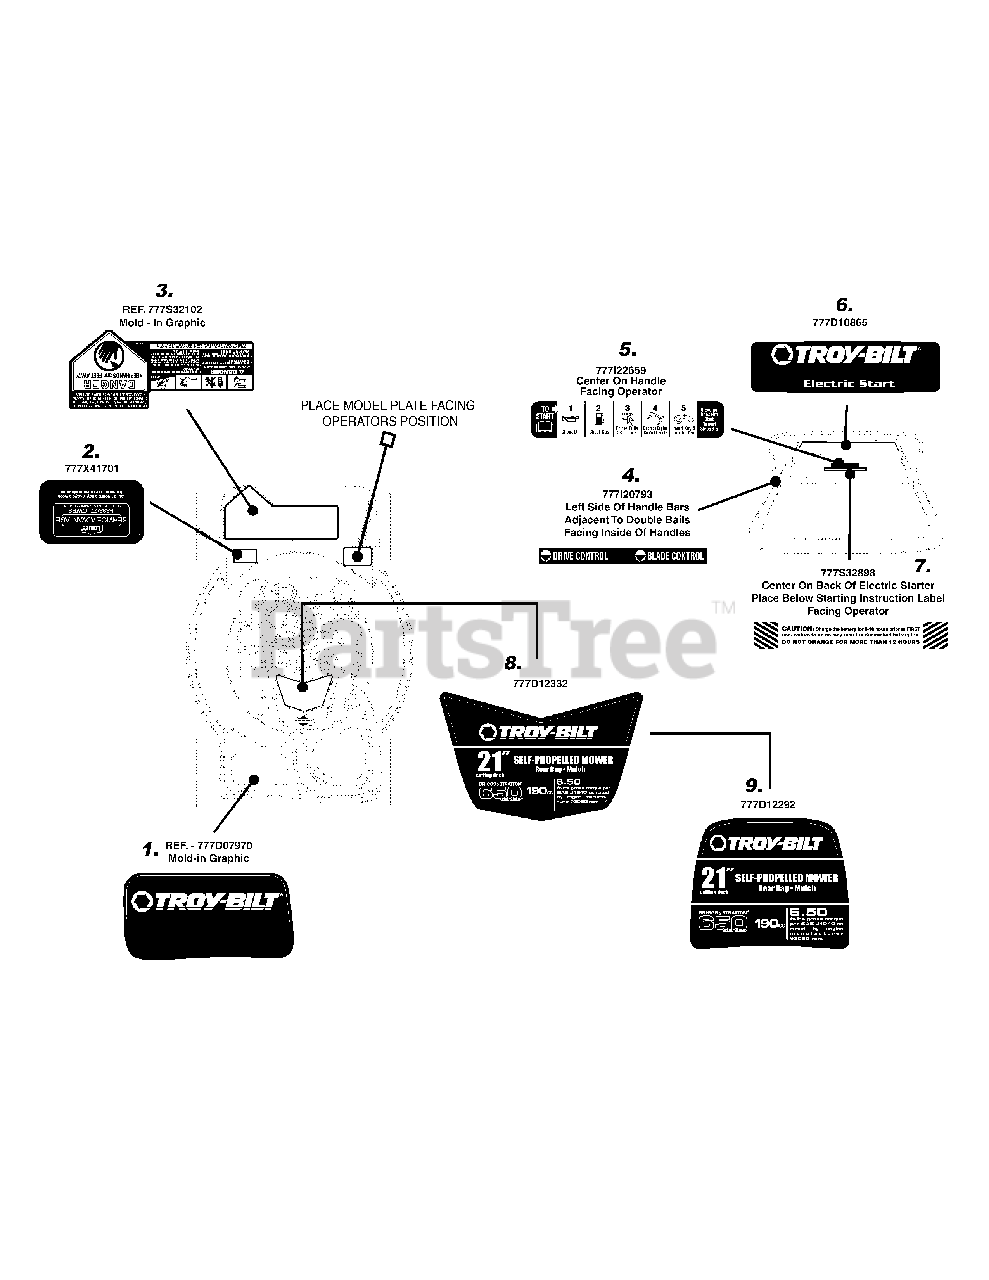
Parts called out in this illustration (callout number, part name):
1	LABEL
2	LBL:LOWES SERVICE ADVANTAGE
3	LABEL
4	LBL:MWR:HNDL:DBL BAIL
5	LABEL-MOWER HANDLE INSTRUCT B&S
6	LBL:MWR:HNDL:TROY:ELEC
7	LABEL-MOWER CHARGE CAUTION
8	LABEL-MOWER SHROUD XKP TROY
9	LABEL-MOWER SHROUD XVS TROY
